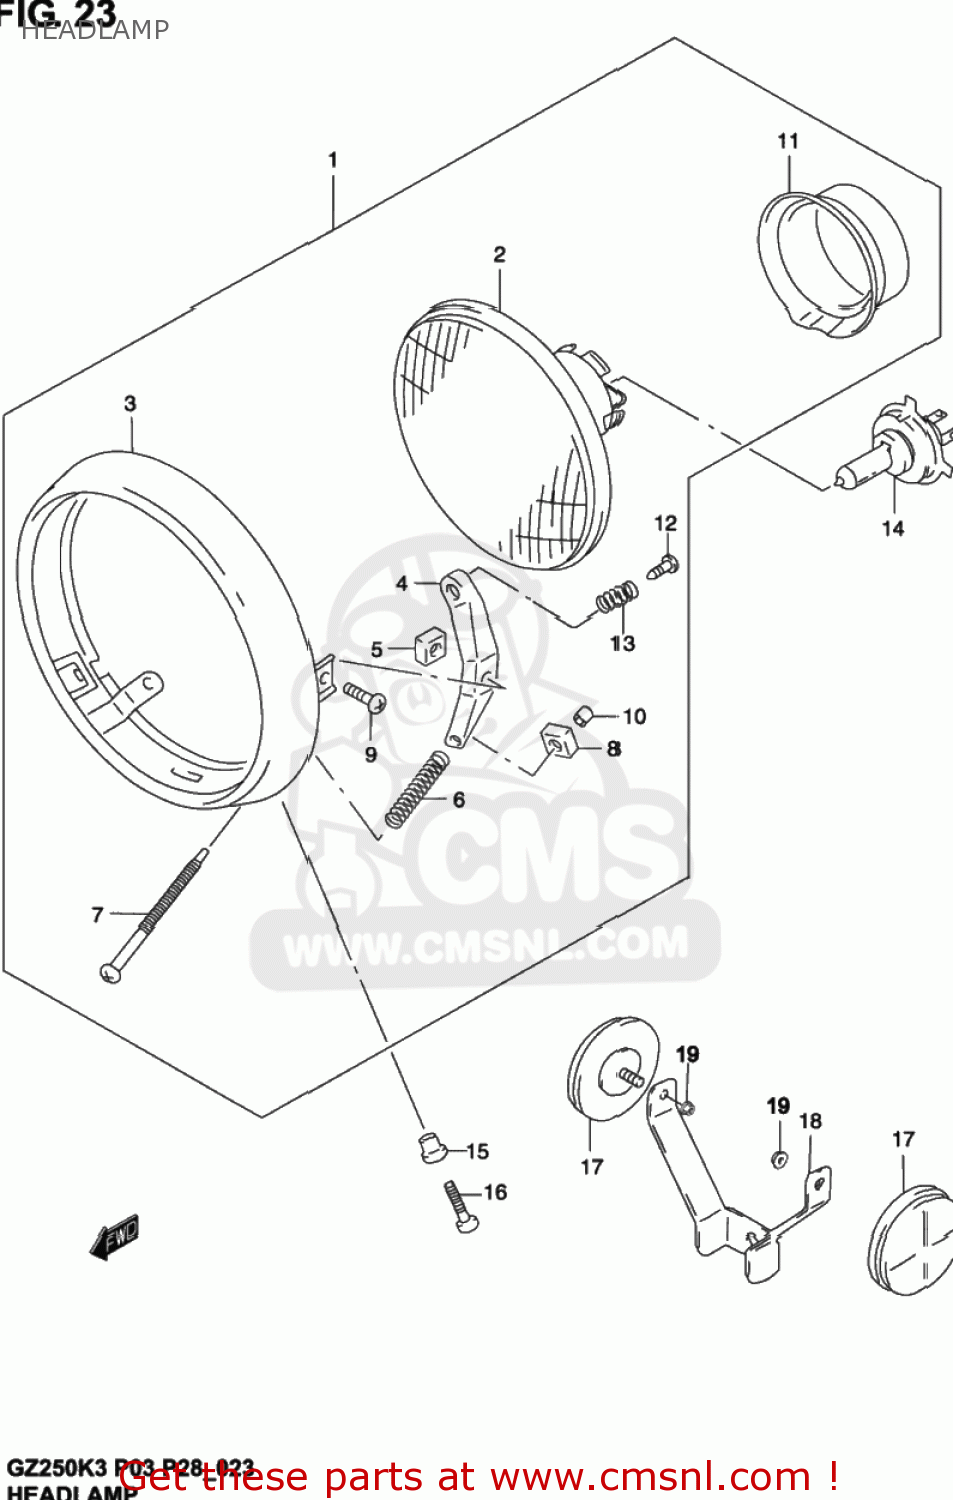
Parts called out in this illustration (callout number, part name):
1	HEADLAMP ASSY
2	UNIT ASSY
3	RIM,HEAD LAMP
4	STAY
5	NUT
6	SPRING
7	SCREW
8	NUT,HEADLAMP ADJUST
9	SCREW
10	CAP,SCREW
11	COVER,SOCKET
12	SCREW
13	SPRING
14	BULB(12V60/55W,H4)
15	SPACER,HEADLAMP
16	SCREW
17	REFLECTOR
18	BRACKET,FR SIDE DEFLECTOR
19	NUT, LICENSE
